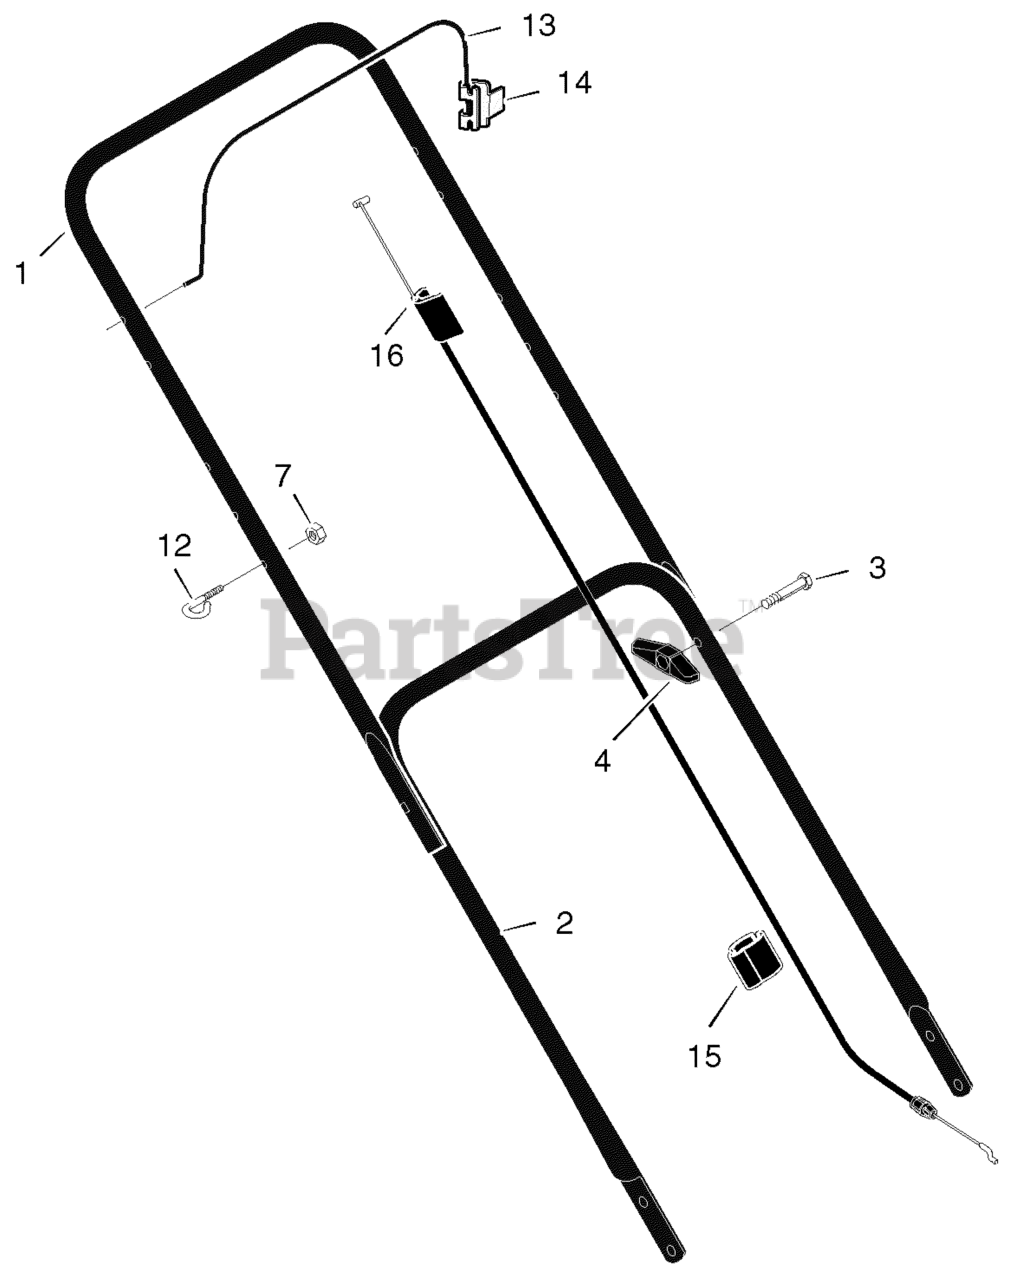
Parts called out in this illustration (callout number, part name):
1	Handle, Upper (Black)
1	Handle, Upper (Gray)
2	Handle, Lower (Black)
2	Handle, Lower (Gray)
4	Knob, Plastic
7	Locknut
12	Guide, Rope
13	Engine Stop Lever
14	Bracket, Stop Lever
15	Fastener, Cable
16	Engine Stop Cable *
